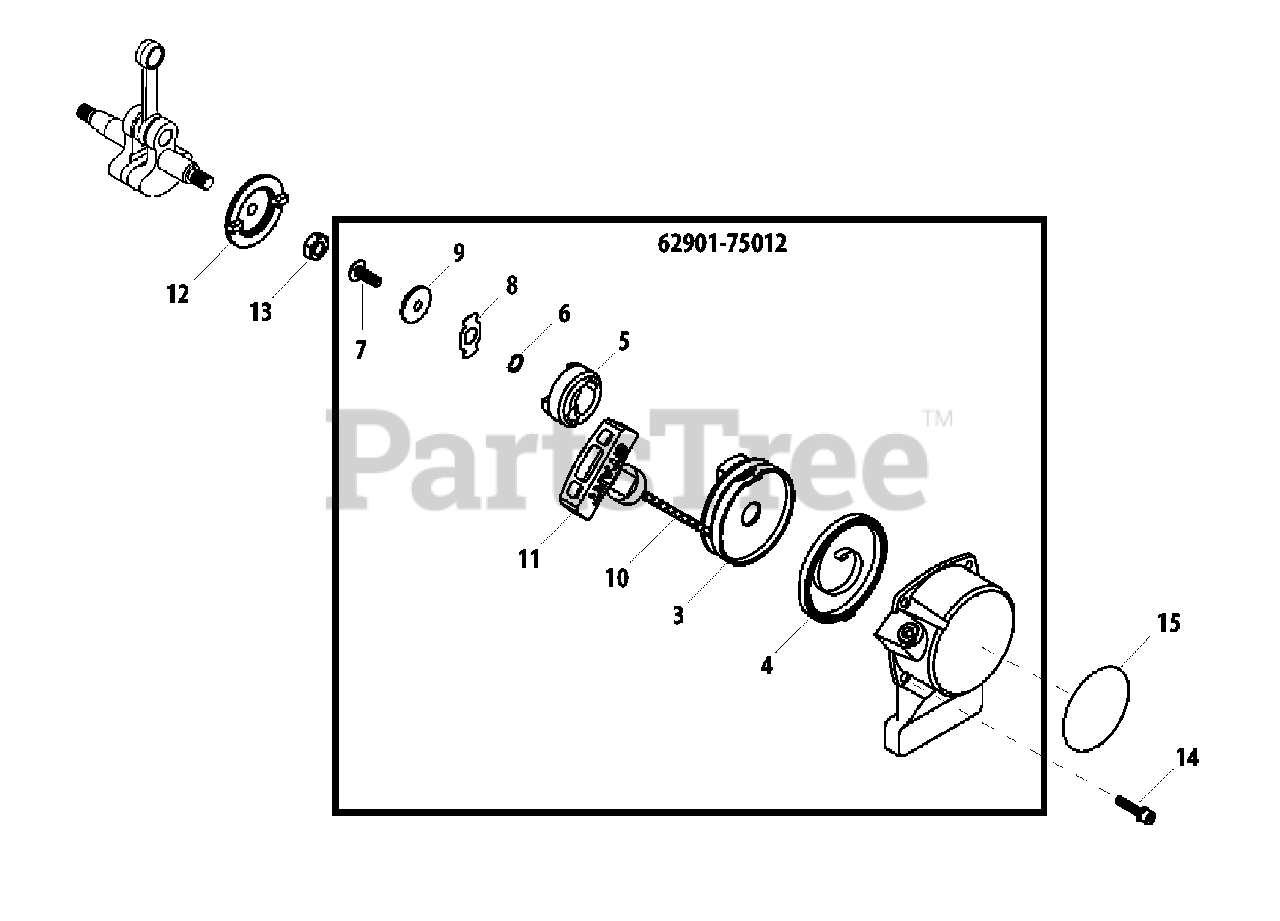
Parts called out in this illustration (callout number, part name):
3	REEL, ROPE
4	SPRING, REWIND
5	PAWL, STARTER
6	WASHER - SPRING
7	SCREW - 5
8	RETAINER
9	WASHER - 5
10	ROPE, STARTER
11	GRIP, STARTER
12	PAWL
13	NUT - 8
14	SCREW - 4X16
15	LABEL - C4
62901-75012	STARTER ASSY
